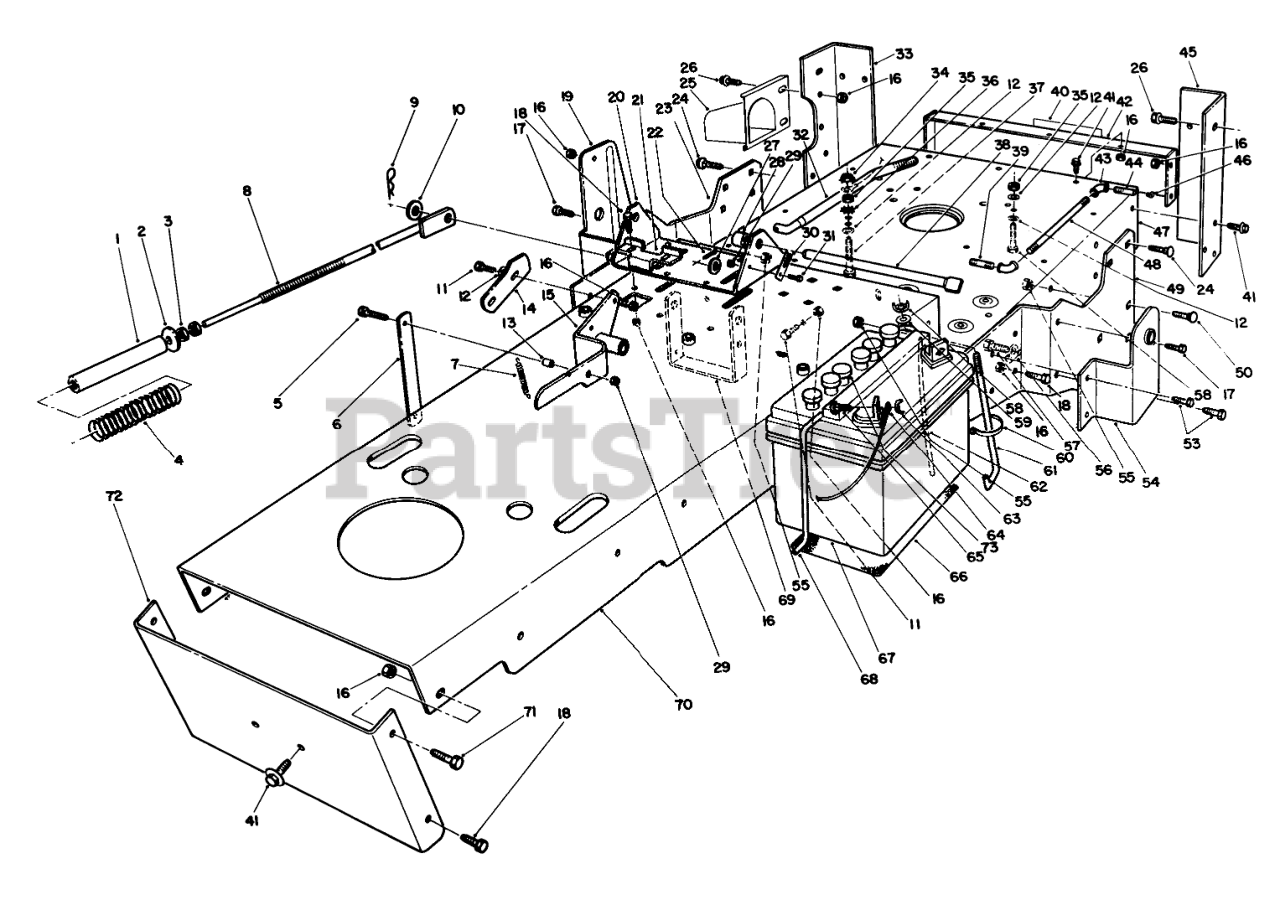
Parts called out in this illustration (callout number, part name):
1	TUBE SLEEVE
2	WASHER
3	NUT-JAM
4	COMP. SPRING
5	SCREW-HH
6	PARKING BRAKE LINK B
7	EXTENSION SPRING
8	BELT TENSION ROD WA
9	PIN-HAIR
10	WASHER-FLAT
11	SCREW-HH
12	WASHER-PLAIN
13	SPACER
14	SHIFT STOP B
15	PARKING BRAKE LVR WA B
16	NUT-LOCK, NI
17	SCREW-HH
18	SCREW-HH
19	RH PIVOT BRACKET B
20	PIVOT BRACKET B
21	PARKING BRAKE STOP
22	PIN-COTTER
23	RH SPLICE PLATE WA
24	BOLT-CARR
25	DEFLECTOR WA B
26	SCREW-HHF
27	WASHER-FLAT
28	SPACER
29	NUT-LOCK, NI
30	RETAINER-SHAFT
31	SCREW-HH
32	BRAKE ROD
33	RH REAR CORNER POST B
34	NUT-KEPS
35	NUT-HEX, SIDE DEFORM
36	WASHER-LOCK
37	SCREW-HH
38	PARKING BRAKE SHAFT
39	NIPPLE 3/8NPTX 1.50
40	DECAL - TRAILER HITCH
41	SCREW-HHF
42	HITCH PLATE
43	90 DEGREE ELBOW
44	OIL DRAIN TUBE
45	LH REAR CORNER POST B
46	PLUG-PIPE, SQH
47	REAR FRAME WA
48	PIPE NIPPLE
49	LH SPLICE PLATE WA
50	BOLT-CARR
52	SCREW-HH
53	SCREW-HH
54	LH PIVOT BRACKET B
55	NUT-LOCK, NI
57	SCREW-HH
58	NUT-WING
59	WASHER-FLAT
60	TIE-CABLE
61	POST-BATTERY
62	TUBE-VENT
63	NUT-WING
64	WIRE ASM
65	BOLT-CARR
66	PAD-SKID, ANTI
67	Battery
68	BATTERY HOLD DOWN
69	BRAKE U BRACKET B
70	FRONT FRAME WA
71	SCREW-HH
72	FRONT COVER B
73	NON-VENTED BATTERY CAP
